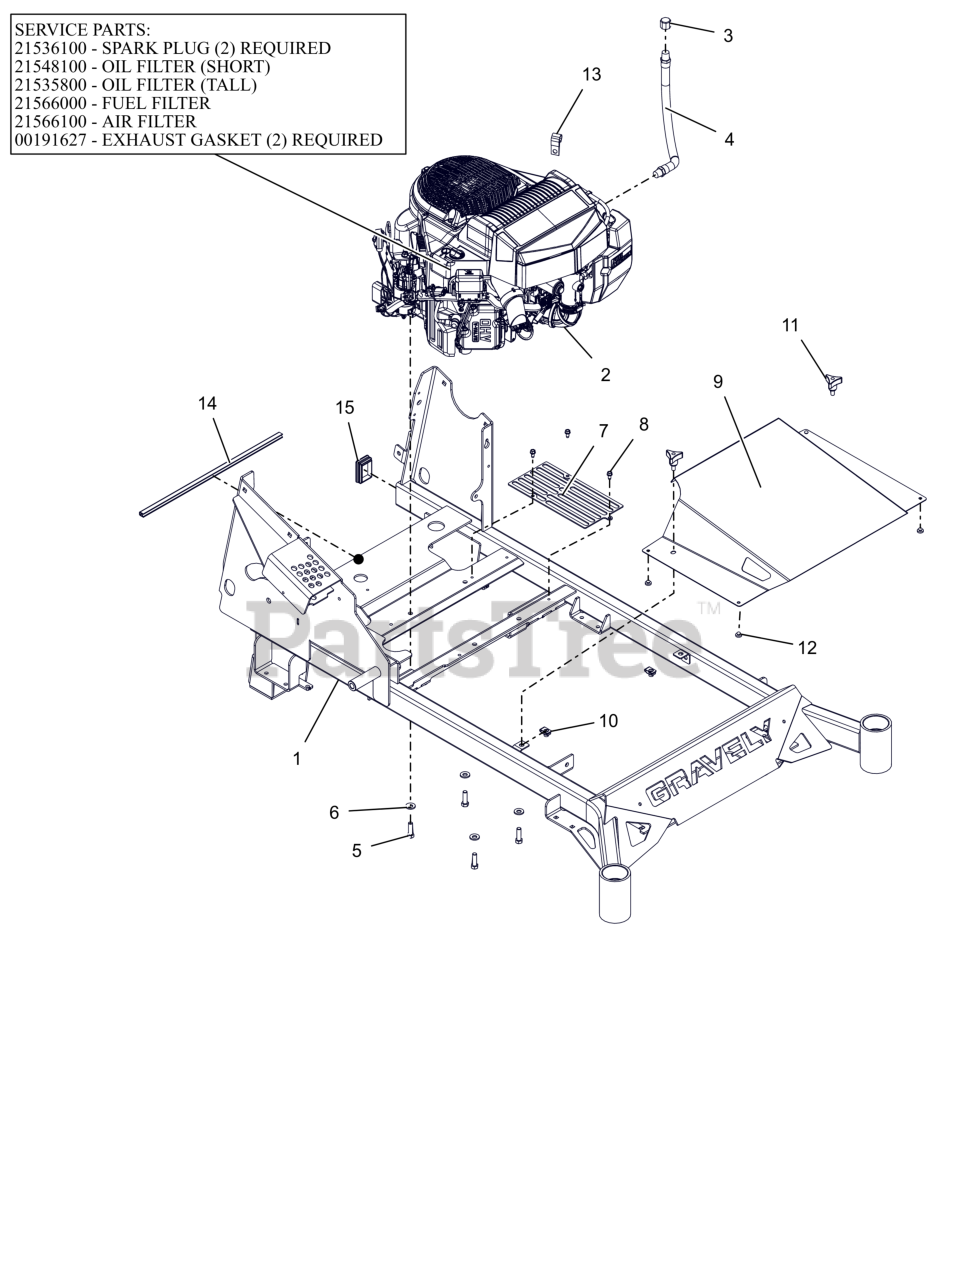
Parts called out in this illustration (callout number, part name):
1	PROSTANCE MAIN FRAME WLDMT-RED
2	ENGINE, KAWASAKI FT730
2	PLUG, SPARK
2	OIL FILTER, KAWASAKI FR
2	FILTER,OIL - KAW
2	FUEL FILTER, KAWASAKI
2	AIR FILTER, KAWASAKI
2	GASKET, MUFFLER S/O
3	PIPE CAP 3/8 NPT FEMALE
4	DRAIN, M20 OIL
5	BLT, HEX .38-16X1.25 G5 ZCC NT
6	WASHER, 3/8" SPRING DISC
7	GUARD, TRANSAXLE FAN (RED)
8	SCR-TAP .25-20X.50 HWH ZCC
9	COVER, BELT
10	NUT-CLIP RETAINER 5/16-18X.56
11	KNOB,WING STUD 5/16-18 X .75
12	BUMPER GROMMET
14	STRIP, COWL
15	PLUG, RECT 1.575 x 2.362
